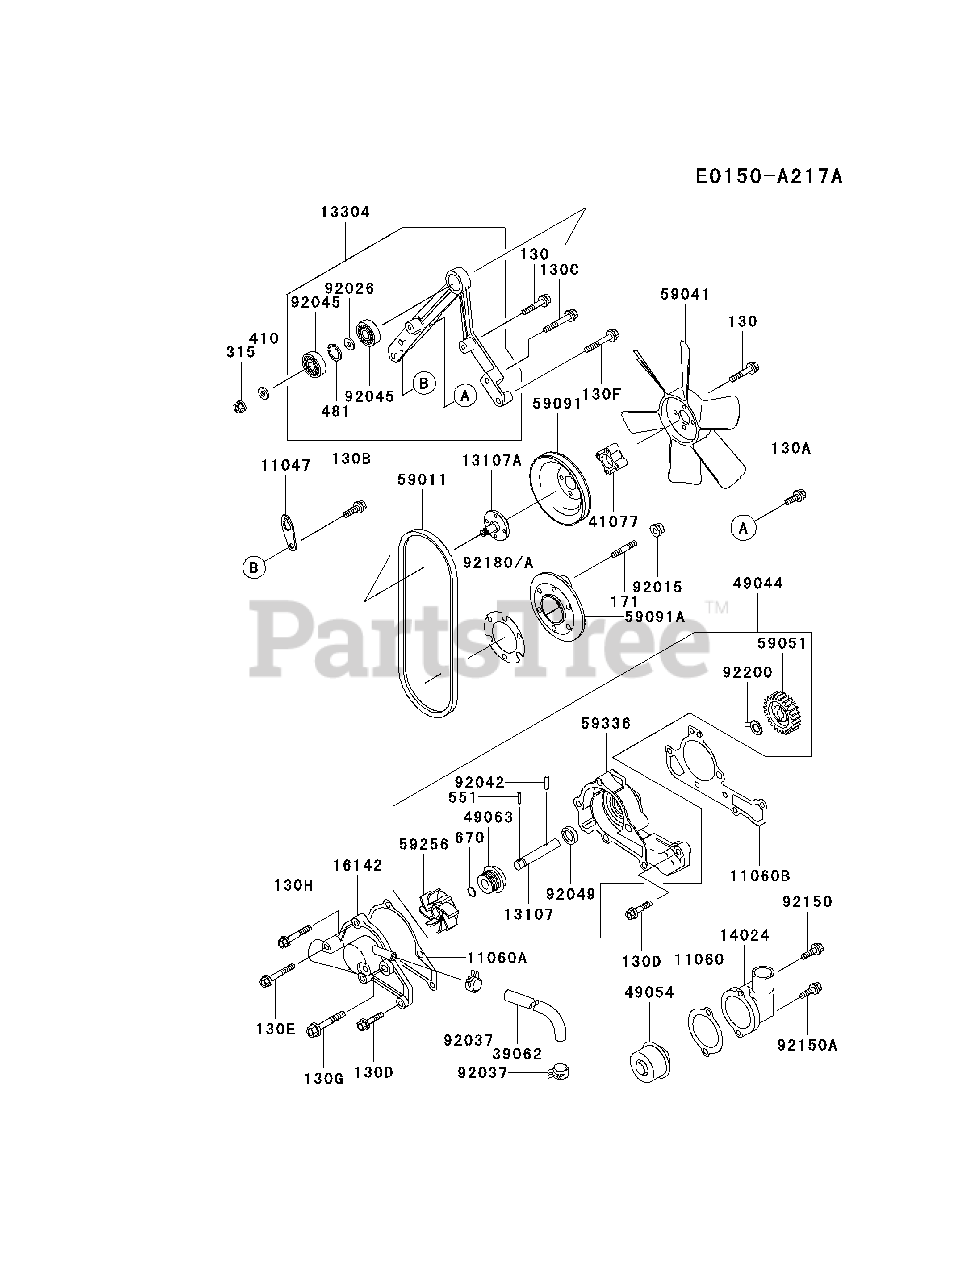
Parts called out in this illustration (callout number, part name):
130H	BOLT-FLANGED
171	BOLT-STUD
315	NUT-HEX-FINE
410	W-PLAIN-S
481	CIRCLIP
551	PIN-DOWEL
670	O RING
